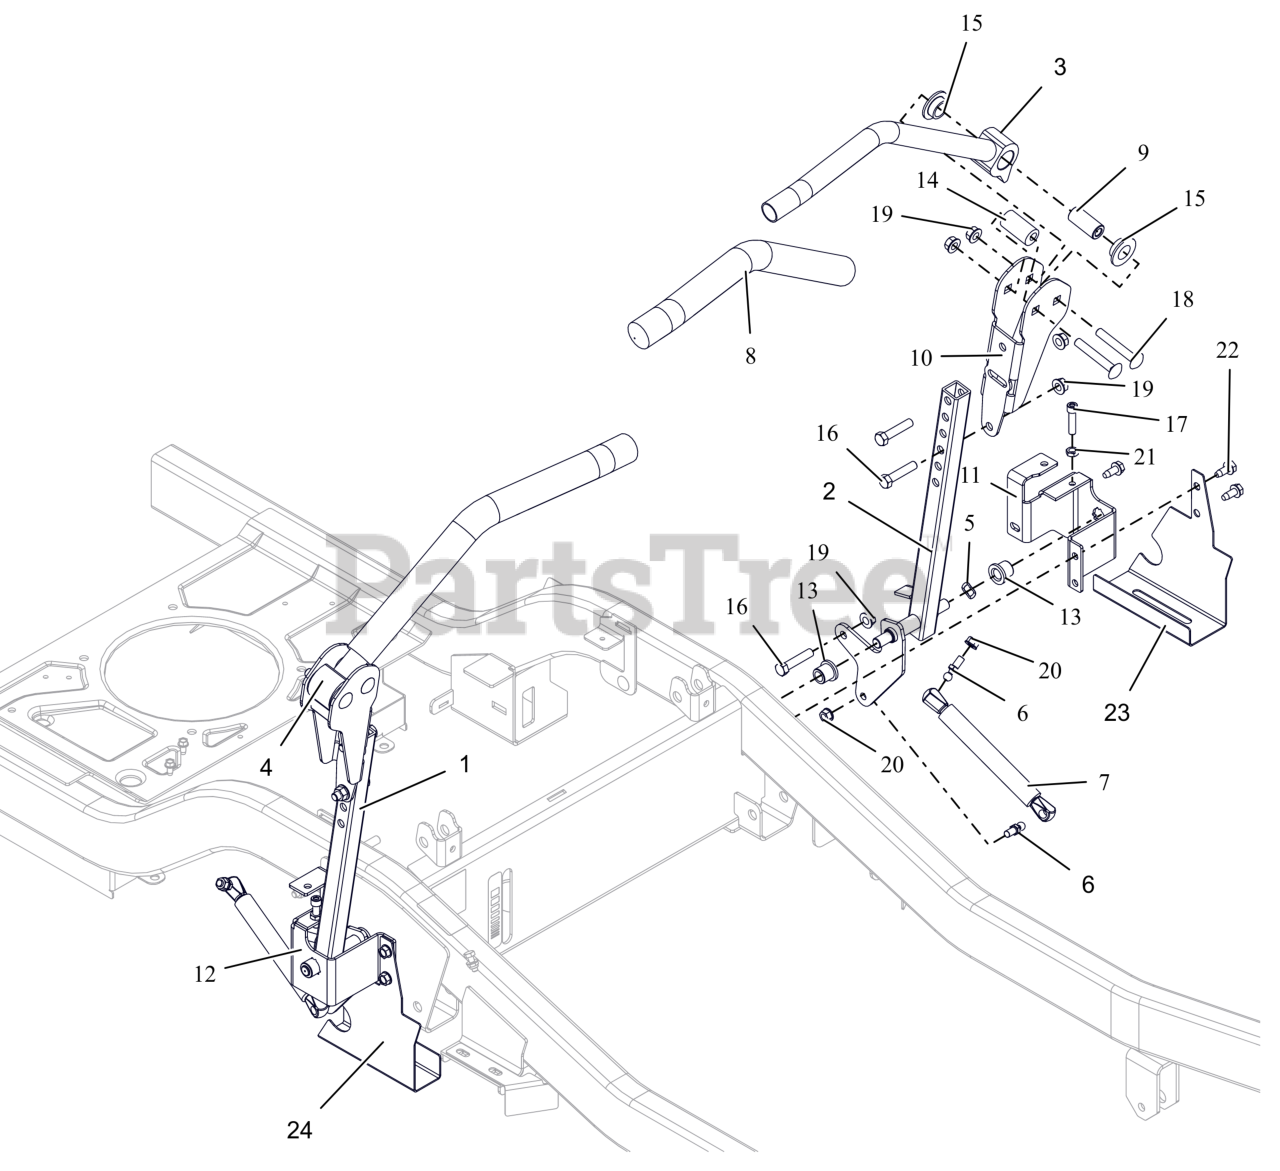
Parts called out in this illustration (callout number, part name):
1	WLDMT, STEERING RH
2	WLDMT, STEERING LH
3	WLDMT, CONTROL HANDLE-LH (BLACK)
4	WLDMT, CONTROL HANDLE-RH (BLACK)
5	WAVE WASHER .531X.781X.125FH
6	STUD- BALL
7	DAMPER
8	GRIP, HANDLEBAR
9	SPACER, STEERING ARM
10	ADJ UPPER CONTROL ARM BRKT-BLK
11	BRKT, STEERING ARM MOUNT -LH
12	BRKT, STEERING ARM MOUNT -RH
13	BHSG-FLG .500X.750X.750X.125
14	BSHG, ECCENTRIC.406X.875X1.625
15	BSHG-FLG .762X1.48X.44 NYL
16	BLT, HEX .38-16X1.75 G5 ZCC
17	BLT, SHCS .312-18X1.25 G8 SS
18	BLT, RHSSN.38-16X2.50 G5 ZCC
19	NUT-LK-TOP-FLG .38-16 ZC120
20	NUT,LK-CTR-FLG .31-18 GF ZCC
21	NUT-JAM .312-18 G2 ZCC
22	SCR,TAP .312-18X.75 HWH TR ZCC
23	GUARD, FRAME RAIL BELT LH (BLACK)
24	GUARD, FRAME RAIL BELT-RH (BLACK)
